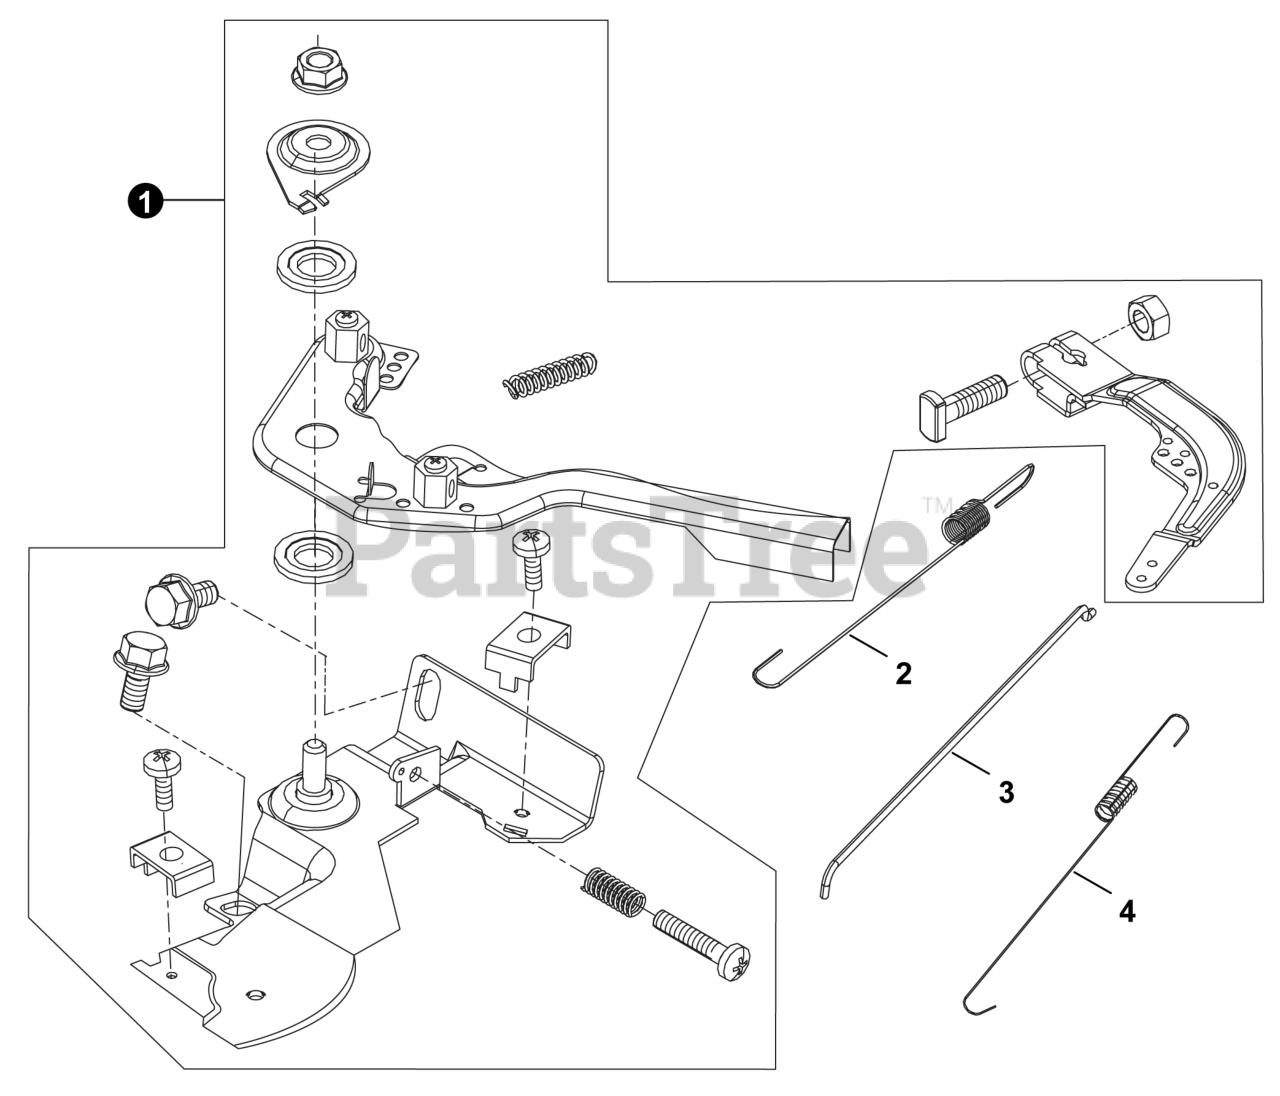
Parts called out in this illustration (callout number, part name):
1	SUPPORT SUBASSEMBLY, GOVERNOR
2	SPRING, GOVERNOR
3	ROD, GOVERNOR
4	SPRING, THROTTLE VALVE RETURNING
